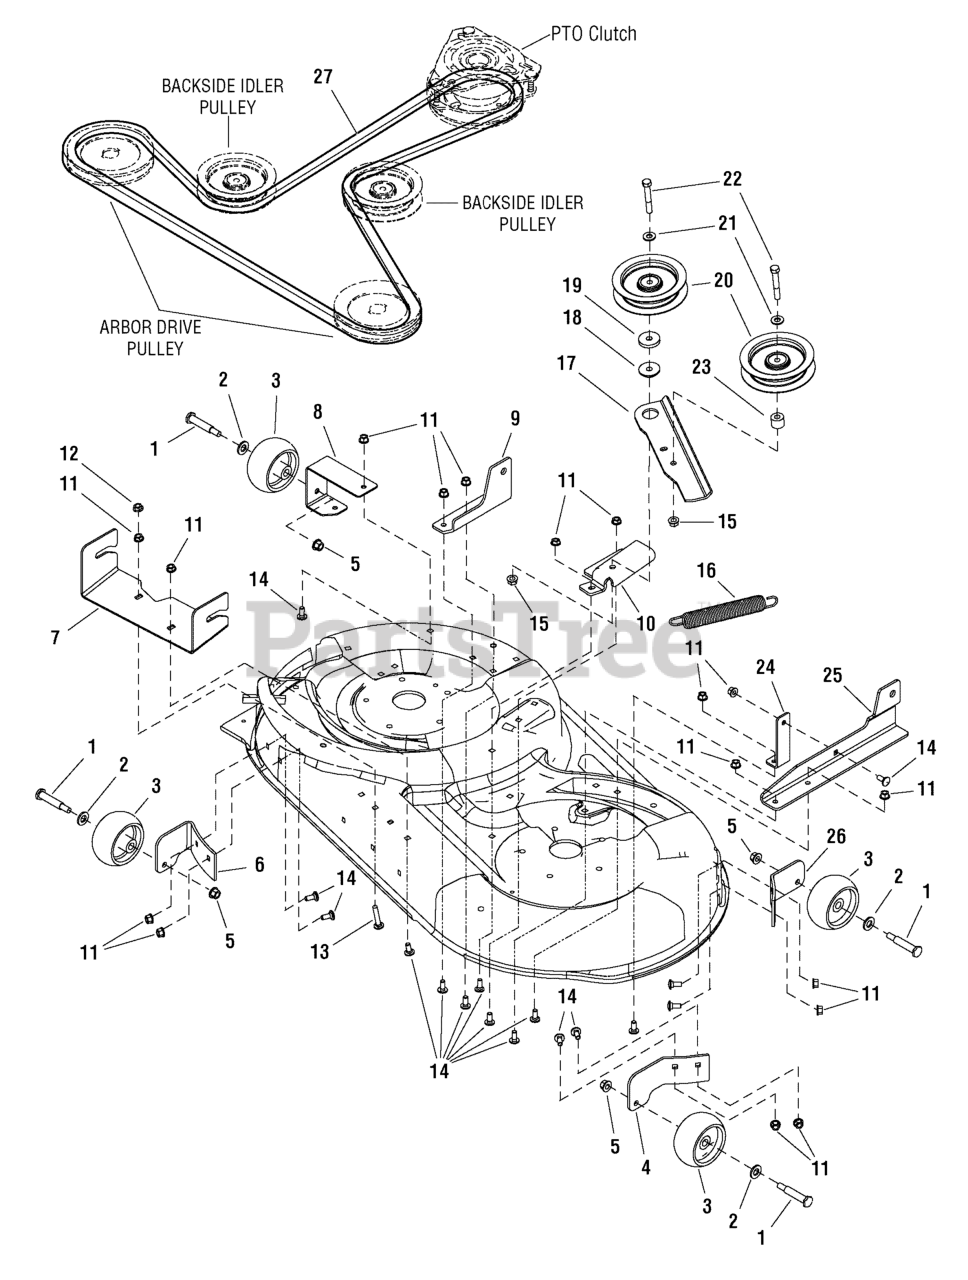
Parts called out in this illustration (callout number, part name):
1	BOLT, Shoulder (Gauge Wheel) 3/8-16 x 2.781 x 3/4
2	WASHER, .51 ID x 1 OD x 1/10 THK
3	GAUGE WHEEL
4	BRACKET, Gauge Wheel L.H. Front
5	NUT, Hex Flange, 3/8-16 ESNA
6	BRACKET, Gauge Wheel R.H. Front
7	HITCH, Mower Front
8	BRACKET, Gauge Wheel R.H. Rear
9	SUPPORT, Mower Rear R.H.
10	BRACKET, Fixed Idler
11	NUT, Hex Flange Whiz Lock, 5/16-18
12	NUT, Hex Two-Way Lock, 5/16-18
13	CARRIAGE BOLT, 5/16-18 x 1-3/4, G5
14	CARRIAGE BOLT, 5/16-18 x 3/4, G5
15	NUT, Hex Flange Whiz Lock, 3/8-16
16	SPRING, Extension
17	ARM, Idler
18	SPACER, Powdered Metal
19	WASHER, 3/8, .41 ID x 1-1/2 OD x 1/4 THK
20	PULLEY, Idler, 4 OD x .378 ID x 1
21	WASHER, 3/8, .41 ID x .87 OD x .08 THK
22	CAPSCREW, Hex Head, 3/8-16 x 2-1/4, G5
24	BRACE, Mower Support
25	SUPPORT, Mower Rear L.H.
26	SUPPORT, Gauge Wheel, LH
27	V-BELT, A-Wedge
